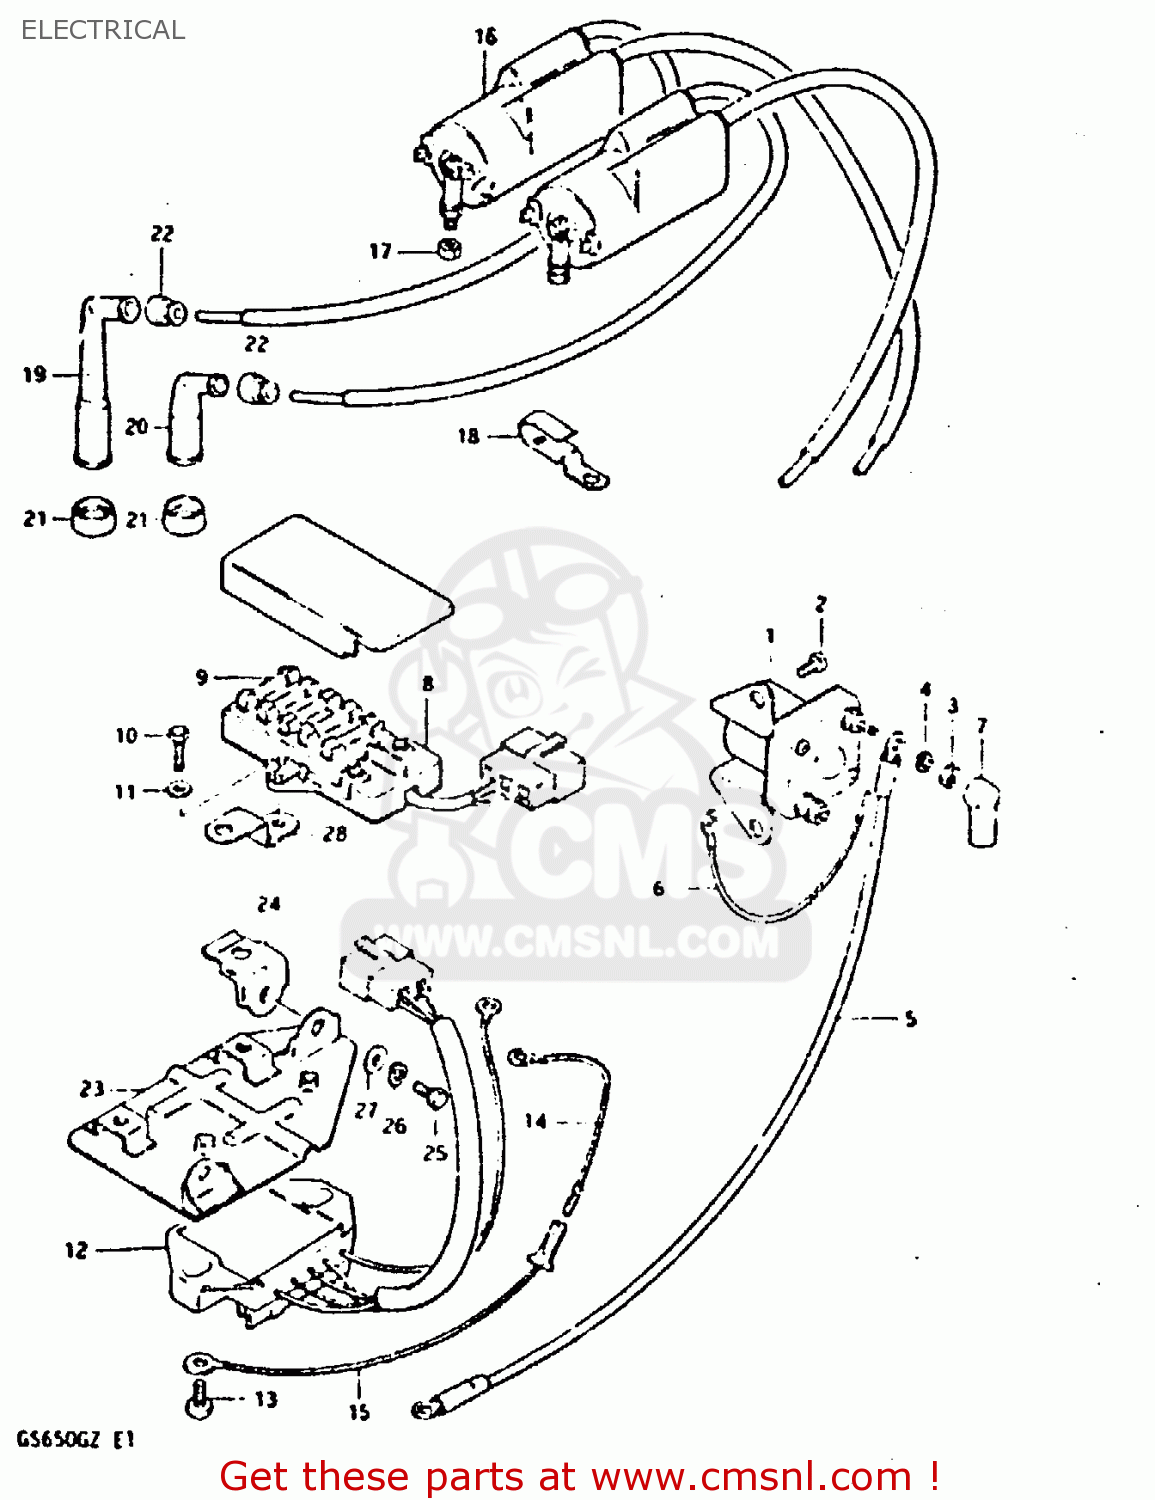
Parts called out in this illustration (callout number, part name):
1	RELAY ASSY,STARTING MOTOR
2	SCREW
3	NUT 6MM
4	LOCK WASHER
5	CABLE,STARTING MOTOR
6	LEAD WIRE
7	CAP,STARTER RELAY
8	BOX ASSEMBLY,FUSE
9	FUSE(15A)
10	BOLT, UPPER
11	WASHER
12	RECTIFIER ASSEMBLY
13	SCREW
14	LEAD WIRE
15	WIRE
16	COIL ASSEMBLY,IGNITION
17	NUT
18	CLAMP
19	CAP ASSY,SPARK PLUG
20	CAP,SPARK PLUG
21	SEAL,SPARK PLUG
22	SEAL,SPARK PLU
23	PLATE,ELECTRIC PARTS H
24	BRACKET, PARTS HOLDER
25	BOLT
26	LOCK WASHER
27	WASHER
28	BRACKET
